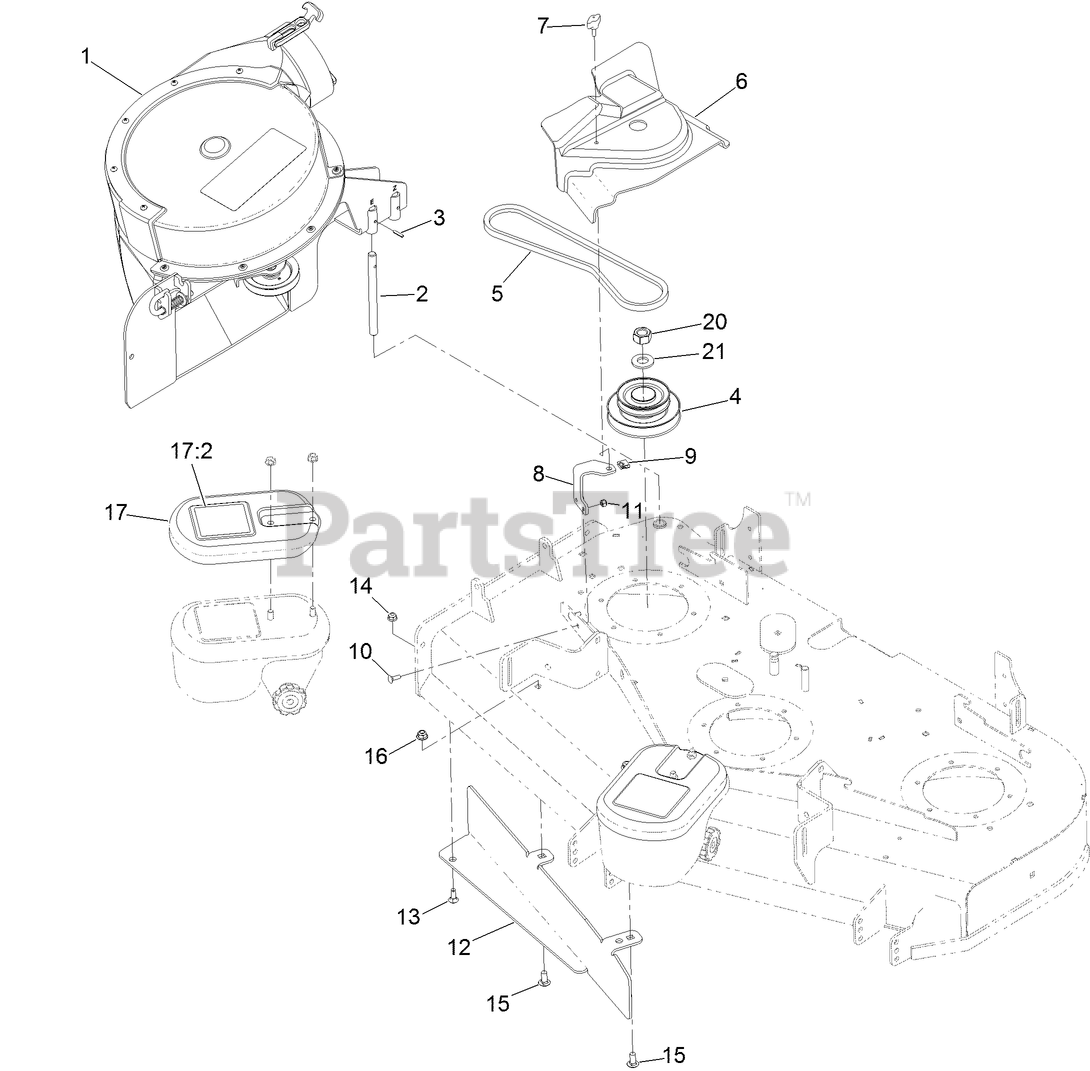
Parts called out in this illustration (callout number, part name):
1	BLOWER ASM
2	SHAFT-CATCHER, GRASS
3	PIN-ROLL
4	DRIVE-JACKSHAFT
5	BELT-V
6	COVER-BELT
8	BRACKET-COVER, BELT
9	NUT-SPEED
10	BOLT-CARR
11	NUT-LOCK, NI
12	BAFFLE-BAGGER
13	SCREW-CARR
14	NUT-HF, NI
15	SCREW-CARR
16	NUT-HF, NI
17	WEIGHT
17:2	DECAL-WARNING, TRACTION
20	NUT-HEX
21	WASHER
